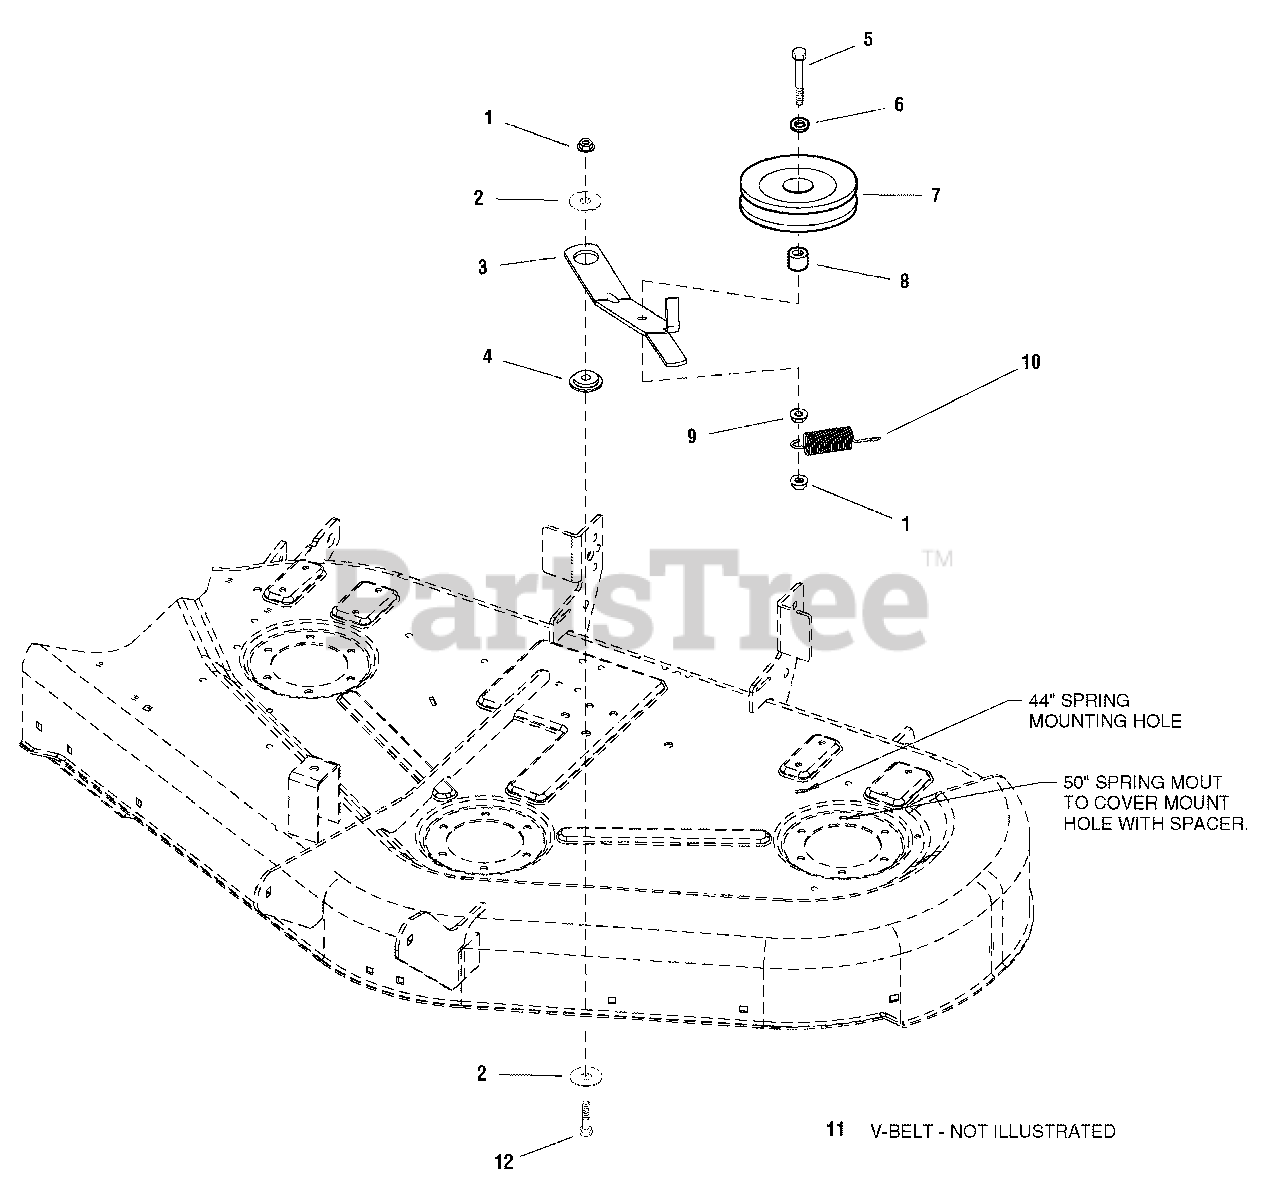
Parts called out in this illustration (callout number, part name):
1	NUT, Hex Flange Center Locking, 3/8-16
2	WASHER, Plain, 13/32 x 1-1/2 x 1/8
3	ARM, Idler 7GA
5	CAPSCREW, Hex Head, 3/8-16 x 2-1/2
6	WASHER, 3/8
7	PULLEY ASSEMBLY
9	NUT, Whizlock, 3/8-16
10	SPRING, Extension, Idler Arm
11	V-BELT, Arbor Drive, 44"
12	CAPSCREW, Hex Head, 3/8-16 x 1-1/4, G8
